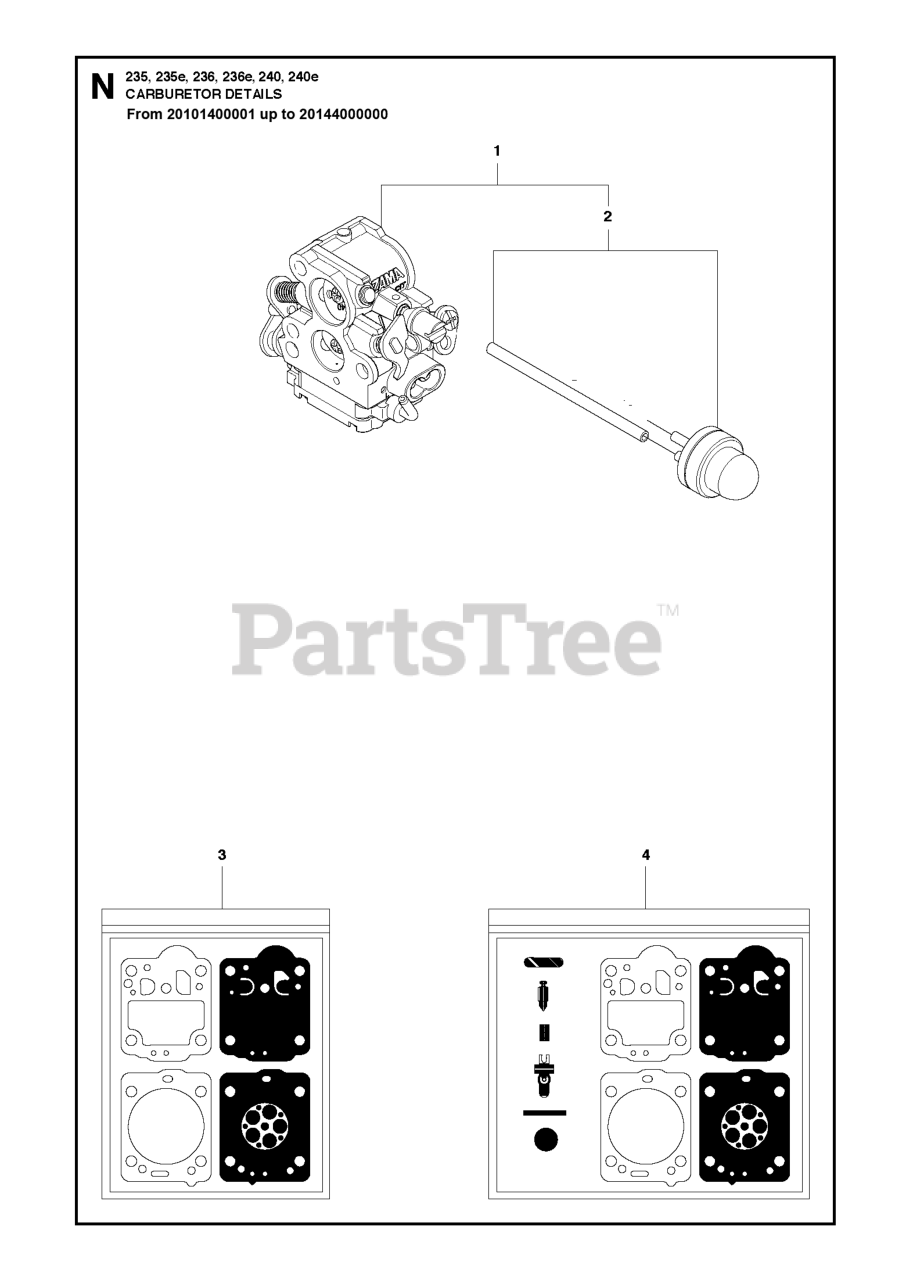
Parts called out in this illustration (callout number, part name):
1	CARBURETTOR 14MM AIR BORE, ANG
2	PURGE & LINE ASSY
3	KIT CARB GASKET
4	KIT CARB REPAIR
